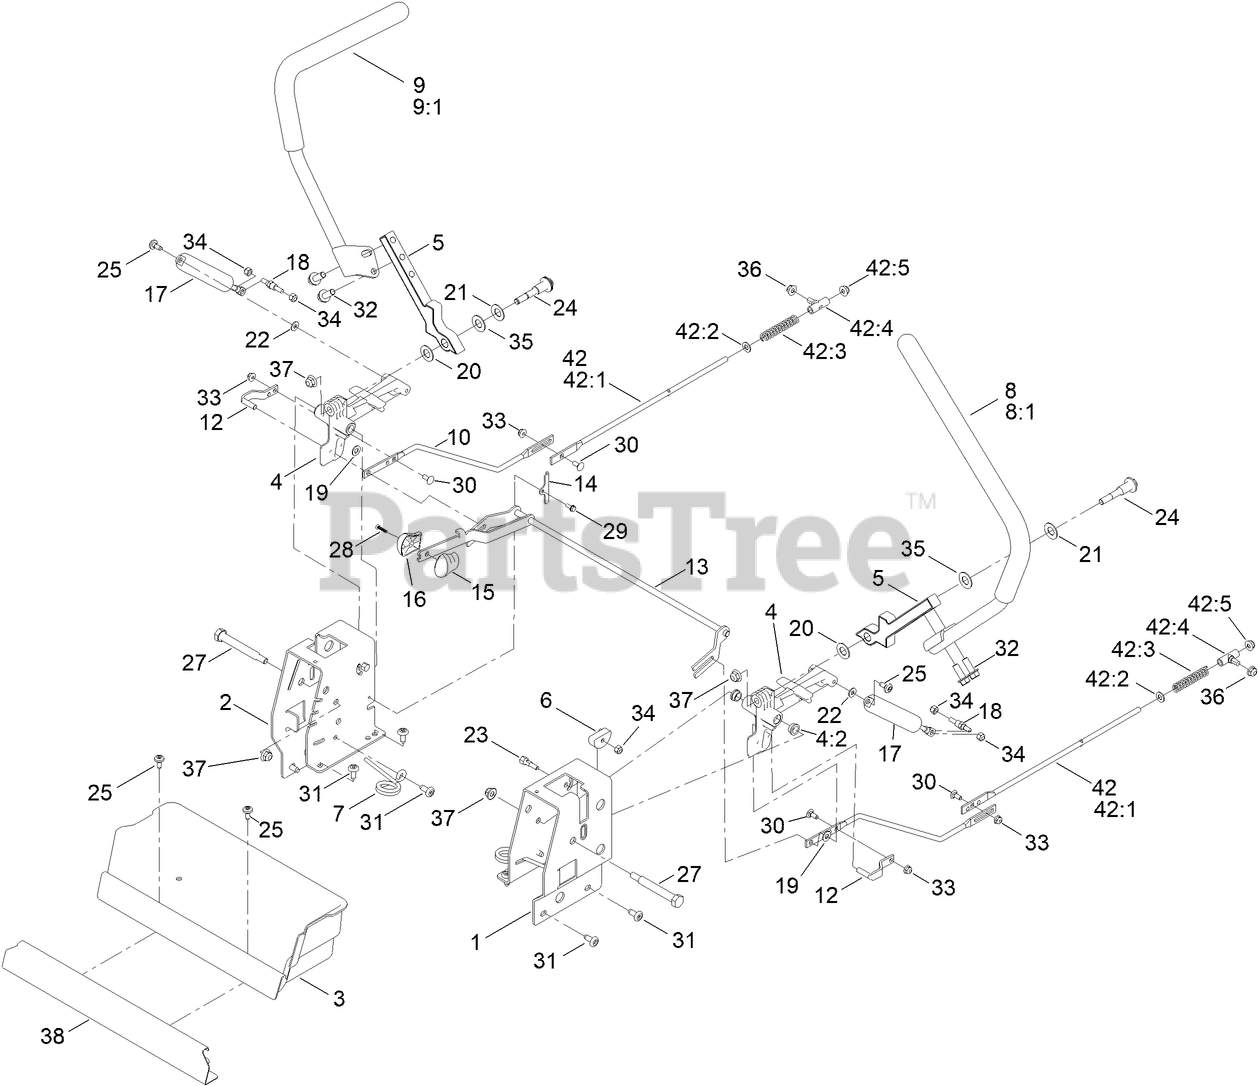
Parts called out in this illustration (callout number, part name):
1	PLATE-CONTROL BOX, LH
2	PLATE-CONTROL BOX, RH
3	BOX-STORAGE
4	ACTUATOR ARM ASM
4:2	BUSHING-FLANGE
5	ARM-CONTROL
6	ECCENTRIC
7	SPRING-TORSION
8	HANDLE-CONTROL, LH
9	HANDLE-CONTROL, RH
10	ROD-HYDRO, FRONT
12	PIN-ROD, HYDRO
13	SPEED CONTROL ASM
14	PLATE-RETAINER
15	KNOB-RH
16	KNOB-LH
17	DAMPER-NON CAVITATING
18	STUD-DAMPER
19	SPACER-NYLON
20	WASHER-NYLON
21	WASHER-BELLEVILLE
22	WASHER
23	BOLT-PIVOT, ECCENTRIC
24	BOLT-PIVOT
25	SCREW-SHOULDER
27	BOLT-PIVOT
28	SCREW-PPH
29	SCREW-TAPTITE
30	BOLT-CARR
32	SCREW-HHF
33	NUT-HF
34	NUT-HEX
35	WASHER
36	NUT-HF
37	NUT-HF, NI
38	PLATE-KICK
42	ROD HYDRO ASM
42:1	ROD-HYDRO, REAR
42:2	WASHER-PLAIN
42:3	SPRING-COMPRESSION
42:4	MOUNT-ROD, HYDRO
42:5	NUT-HF
